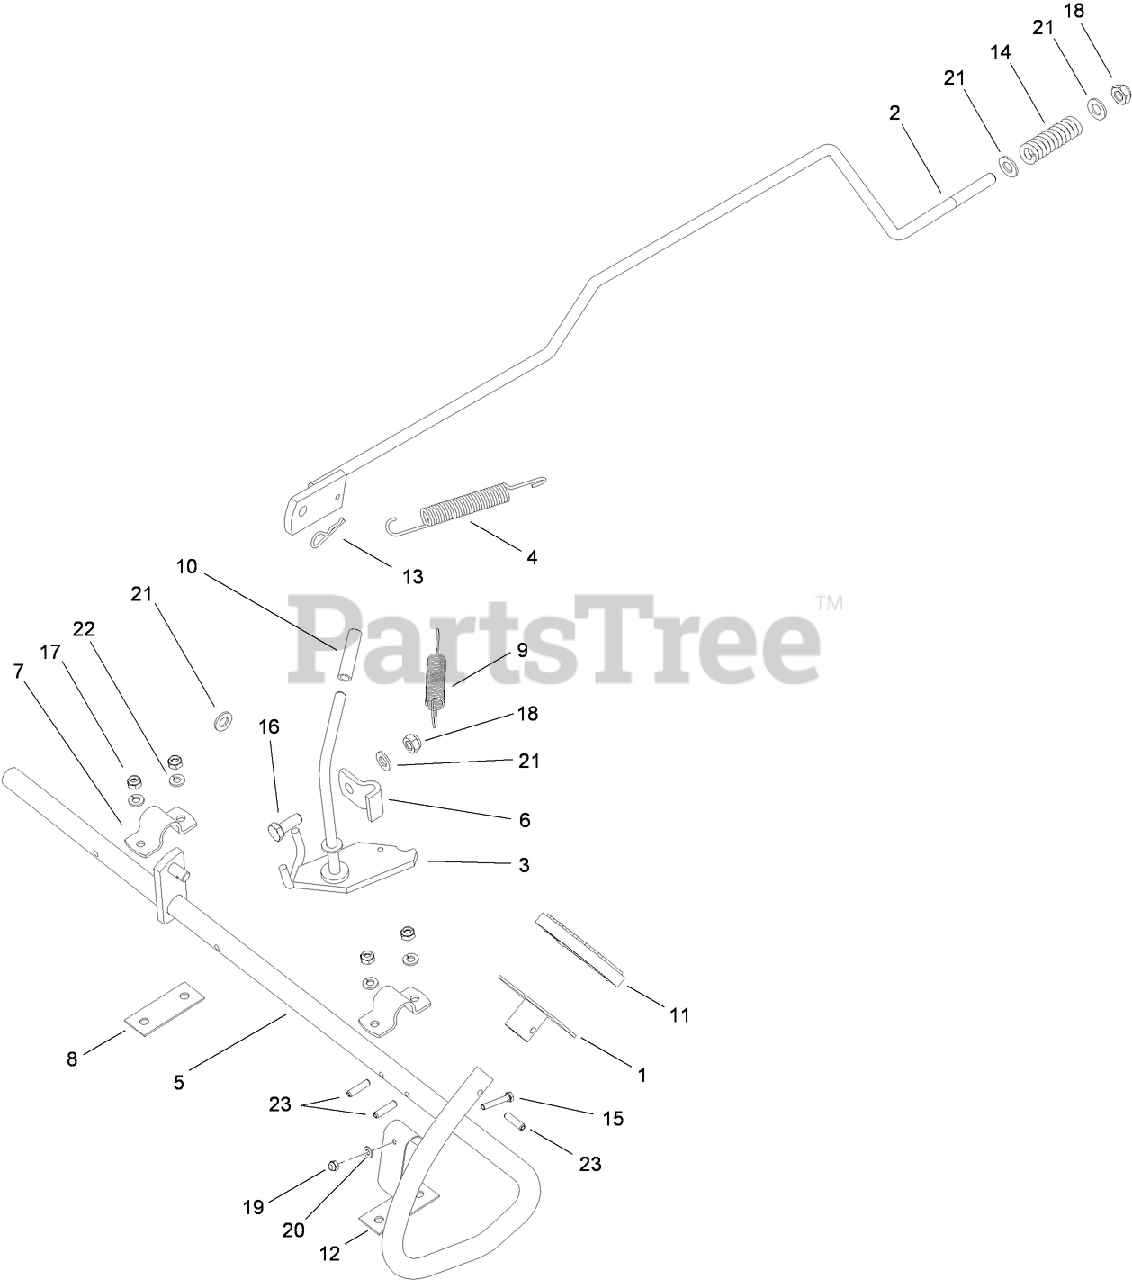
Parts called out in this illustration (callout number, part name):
1	PEDAL-PAD,
2	ROD-BRAKE LINKAGE
3	LEVER-PARKING BRAKE
4	SPRING
5	PEDAL-TRAVEL, BRAKE
9	SPRING-BRAKE, HAND
11	PAD-PEDAL
12	BRACKET-PARKING BRAKE
13	PIN-COTTER
14	SPRING-BRAKE
15	SCREW-HEX
16	SCREW-HH
17	NUT-LOCK
18	NUT-LOCK, NI
19	NUT-HEX
20	Washer
21	WASHER-PLAIN
22	WASHER-SPRING
23	PIN-SPRING
